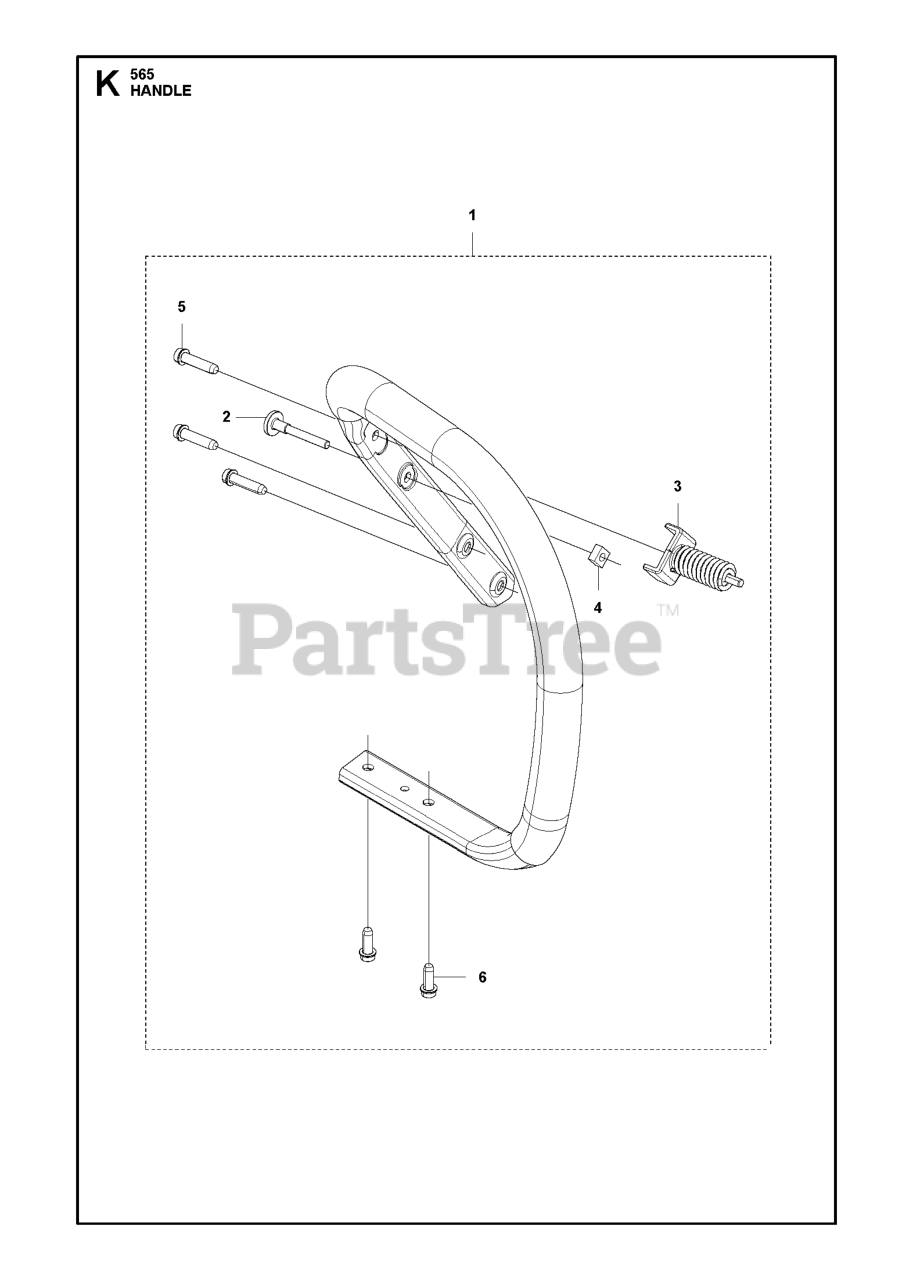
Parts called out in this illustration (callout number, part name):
1	FRONT HANDLE ASSY KIT STANDARD
2	SCREW ITXPANM MOVEMENT LIMITER
3	ANTIVIBRATION ELEMENT CYLINDER
